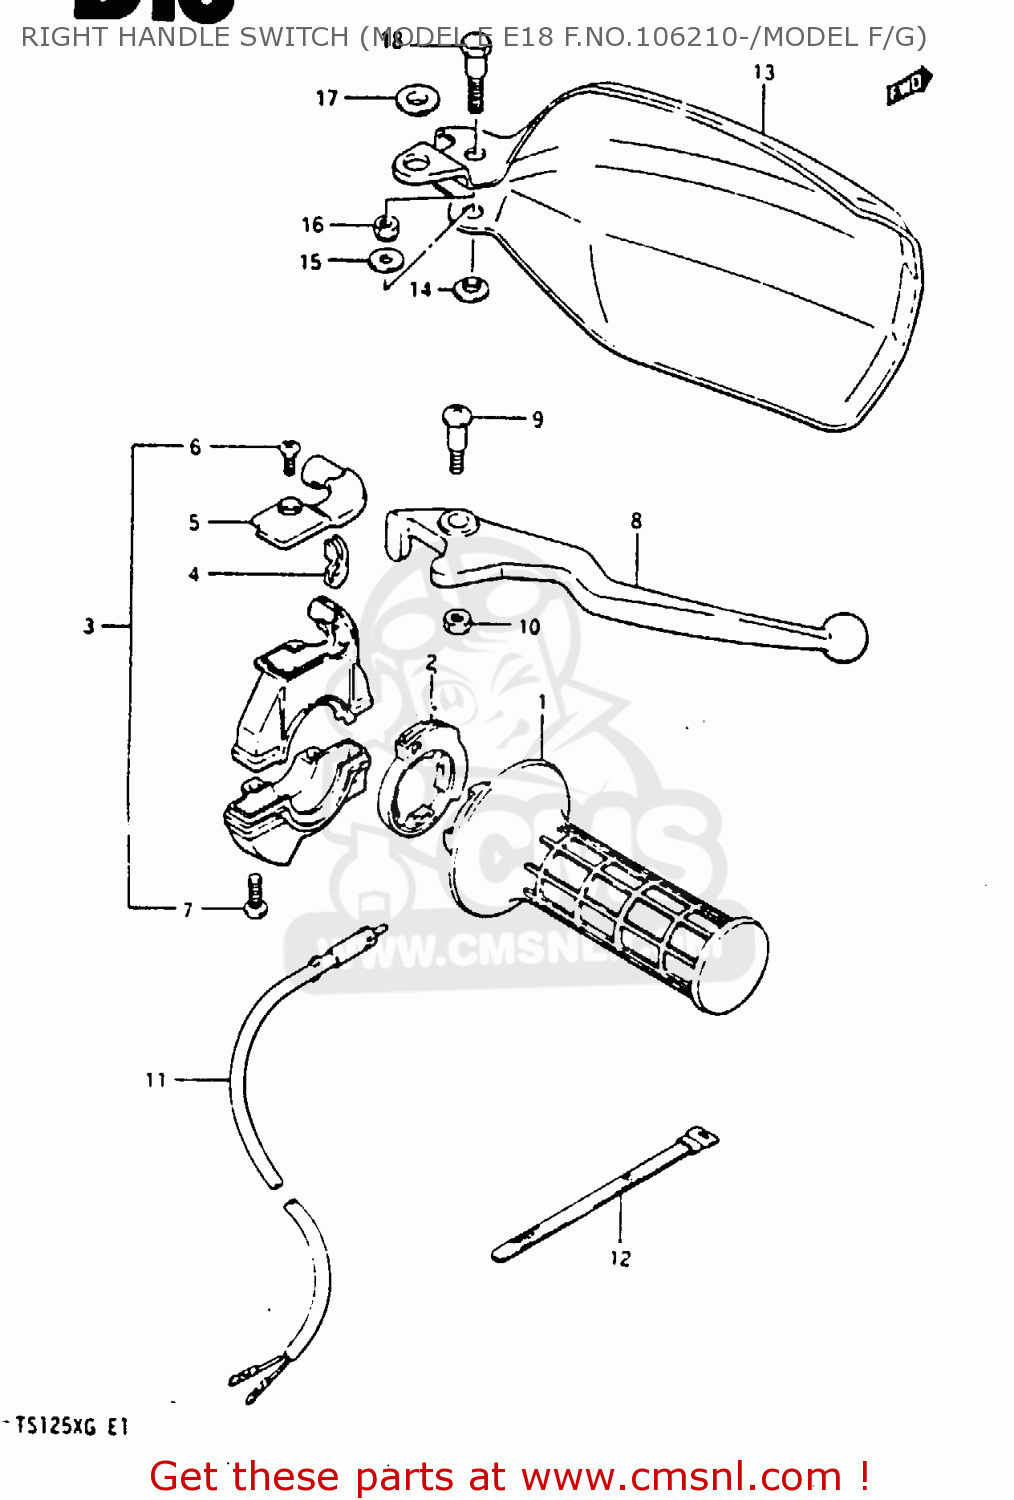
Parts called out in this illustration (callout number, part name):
1	GRIP, THROTTLE
2	ROTOR,THROTTLE GRIP
3	CASE ASSY,THROTTLE
4	GUIDE PIECE,THROTTLE
5	COVER,THROTTLE CASE
6	SCREW
7	SCREW
8	LEVER,BRAKE
9	SCREW
10	NUT
11	SWITCH ASSEMBLY
12	CLAMP(L:120)
13	COVER,KNUCKLE,RIGHT
14	WASHER
15	WASHER(6.5X16X1.2)
16	NUT 6MM
17	WASHER
18	BOLT,LEVER PIVOT
